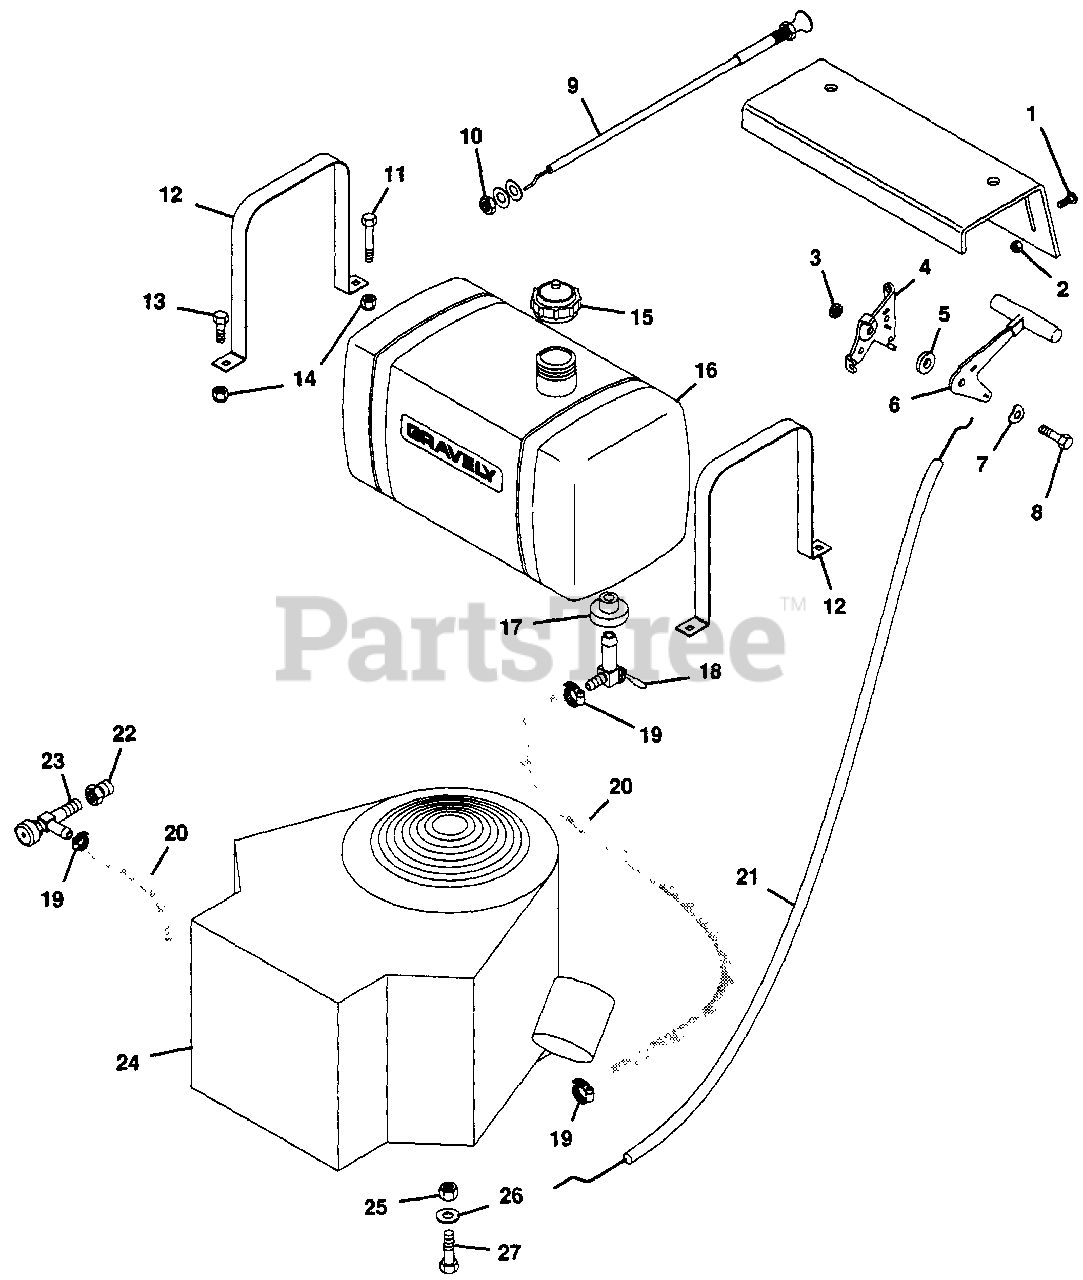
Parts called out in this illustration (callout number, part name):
1	Screw, Mach. 10-32x.50 PHD
2	Nut, Lock 10-32
3	Nut, Lock 1/4-28
4	Bracket, Mounting L.H.
5	Washer, Friction
6	Assembly, Knob and Lever
7	Washer, Spring
8	Bolt, Hex 1/4-28x.75
9	Control, Choke
10	Nut, Jam 3/8-24 Hex
11	Bolt, Hex 1/4-20x1.75
12	Strap, Fuel Tank
13	Bolt, Hex 1/4-20x.625
14	Nut, Lock 1/4-20
15	Cap, Fuel Tank
16	Tank, Fuel
17	Bush., Flg. .375x1.06x.625 Rb.
18	Valve, Ball Shut-off
19	Clamp, Hose
20	Fuel Line 2 feet long
21	Assembly, Throttle Conduit
22	Adaptor, Oil Drain
23	Cock, Oil Drain
24	Engine, 16 HP B&S
25	Nut, Lock 5/16-18
26	Washer, Flat .344x.688x.065
27	Bolt, Hex 5/16-18x1.50
